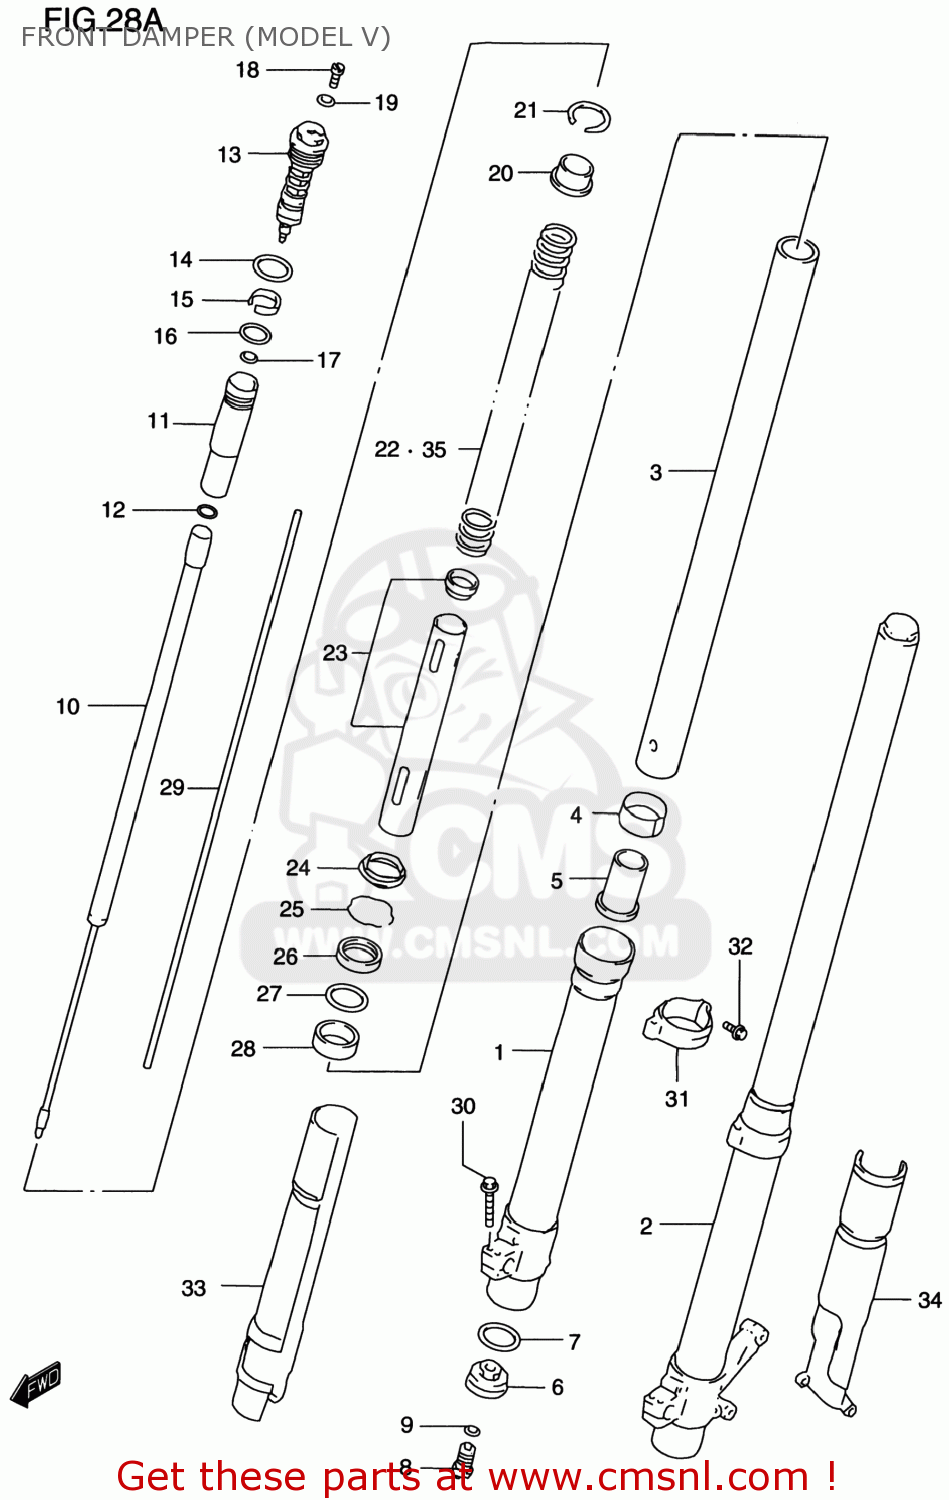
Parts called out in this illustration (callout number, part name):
1	TUBE,OUTER,RIGHT
2	TUBE,OUTER,LEFT
3	TUBE,INNER
4	BUSH,SLIDE
5	PIECE,OIL LOCK
6	PLATE,END
7	O RING
8	BOLT,CTR
9	O RING
10	ROD,FR DAMPER
11	TANK,SUB
12	O-RING
13	BOLT,FORK
14	O RING
15	BUSH,FORK BOLT SLIDE
16	O RING
17	O RING
18	BOLT,PLUG
19	O RING,PLUG
20	SPRING,STOPPER
21	RING,STOPPER
22	SPRING,FRONT (K=0.42)
23	COLLAR,SPRING
24	SEAL,DUST
25	RING,STOPPER
26	SEAL,OIL
27	SPACER,SEAL
28	BUSH,GUIDE
29	ROD,PUSH
30	BOLT,HANDLE HOLDER(8X35)
31	GUIDE,FR PROTECTOR,R
32	BOLT,PROTECTOR GUIDE,6
33	PROTECTOR,OUTER TUBE,R
34	PROTECTOR,OUTER TUBE,L
35	SPRING,FR(K=0.40)
